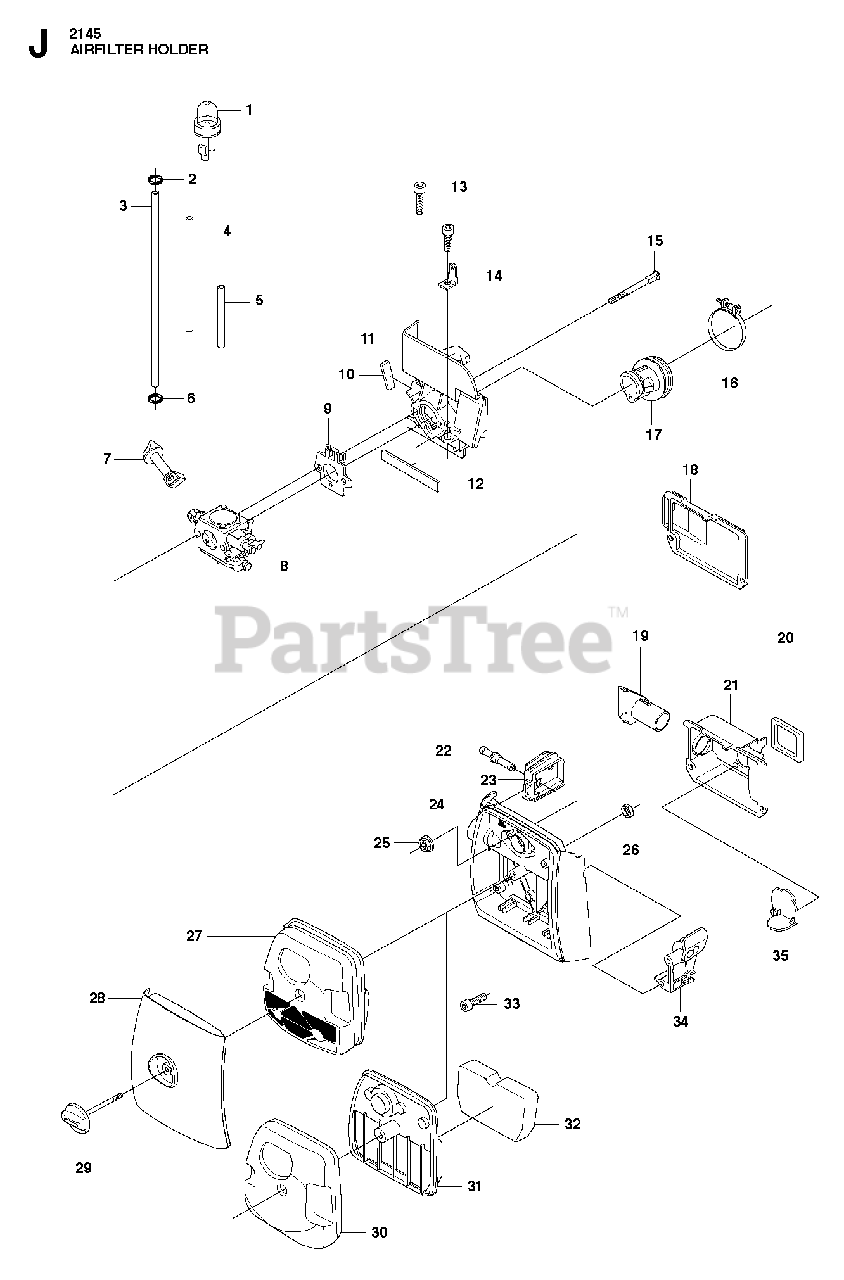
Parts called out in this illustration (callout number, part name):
1	AIR PURGE BUBBLE
3	FUEL HOSE
4	HOSE
5	NOSE
7	CHOKE CONTROL
8	CARBURETOR
9	SPACER WASHER
11	PARTITION
16	CLAMP
18	COVER
19	AIR CONDUCTOR
20	SEAL
21	AIR CAN
24	FILTER HOLDER
26	NUT M6M M5
27	AIR FILTER
28	AIR FILTER COVER
29	HANDLE AIR FILTER COVER
30	COVER
31	BASE
35	COVER
